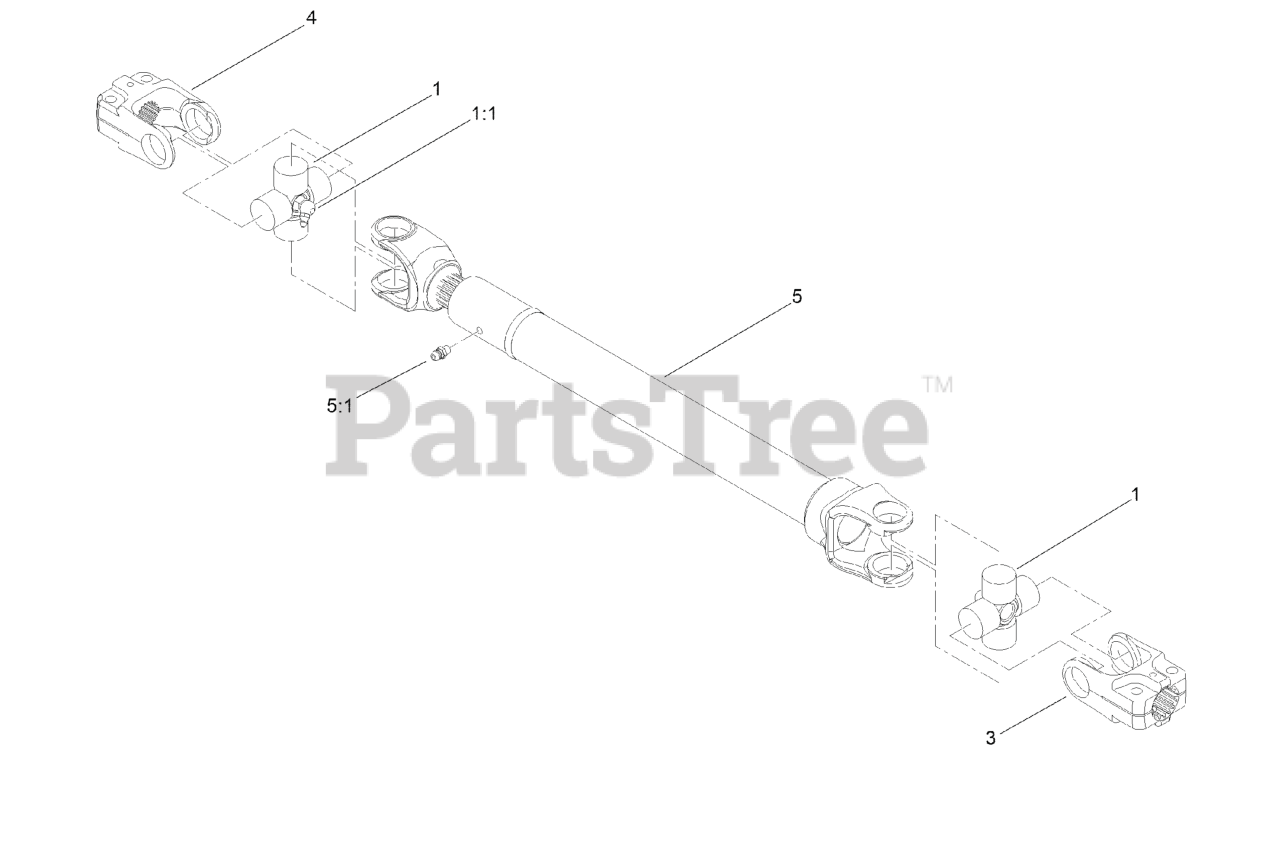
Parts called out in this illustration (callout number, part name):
1	CROSS AND BEARING KIT
1:1	FITTING-GREASE
3	YOKE-END
4	YOKE-END
5	Tube-Yoke, Slip
5:1	FITTING-GREASE
